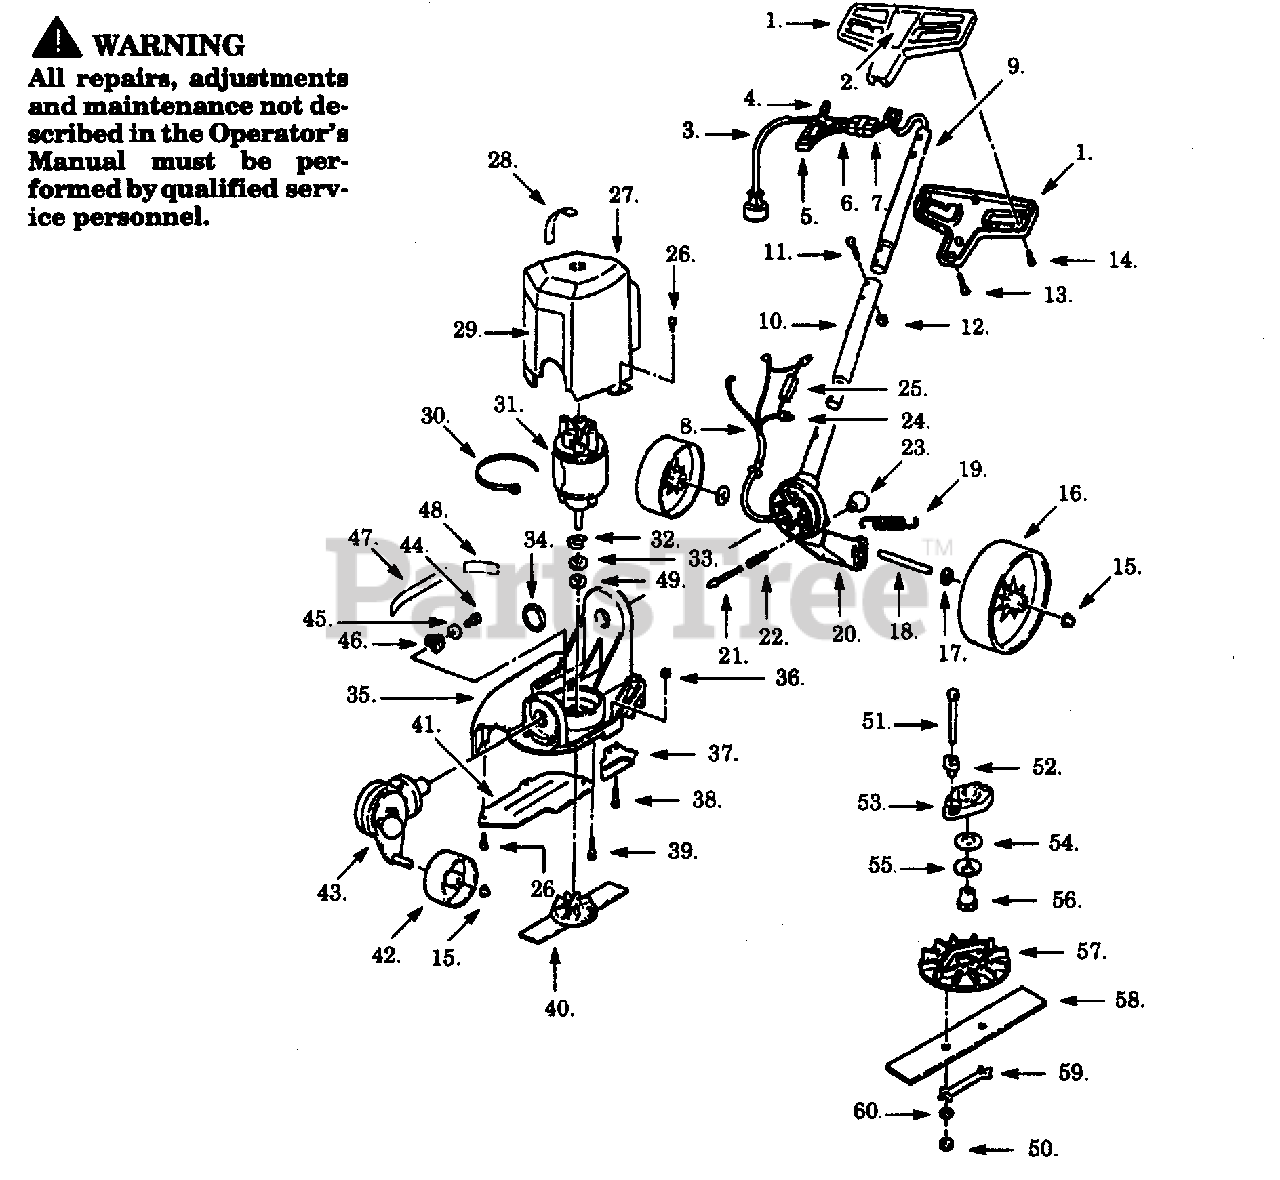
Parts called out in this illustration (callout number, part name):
1	Handle Set
2	Handle Label (Not a serviceable part)
3	Power Cord
4	Wire Nut
6	P.C. Board Ass'y.
7	Insulator
8	Harness Ass'y.
9	Upper Tube
10	Lower Tube
15	Push Nut
16	Rear Wheel
18	Rear Axle
20	Rear Swivel
21	Swivel Lock Shaft
22	Swivel Lock Spring
24	Terminal Cap
25	Resister
27	Motor Cover
28	Rear Adjust Label (Not a serviceable part)
29	Motor Cover Label (Not a serviceable part)
30	Tie Wrap
31	Motor Ass'y.
32	Retaining Ring
34	Retaining Ring
35	Deck Frame
37	Blade Guide
40	Blade Ass'y.
41	Side Guard Plate
42	Front Wheel
43	Front Swivel Ass'y.
46	Front Swivel Spring
47	Dyn Brake Label (Not a serviceable part)
48	Warning Label (Not a serviceable part)
52	Insulating Sleeve
53	Clutch Plate
55	Spring Washer
56	Clutch Sleeve
59	Lock Strap
60	Lockwasher
